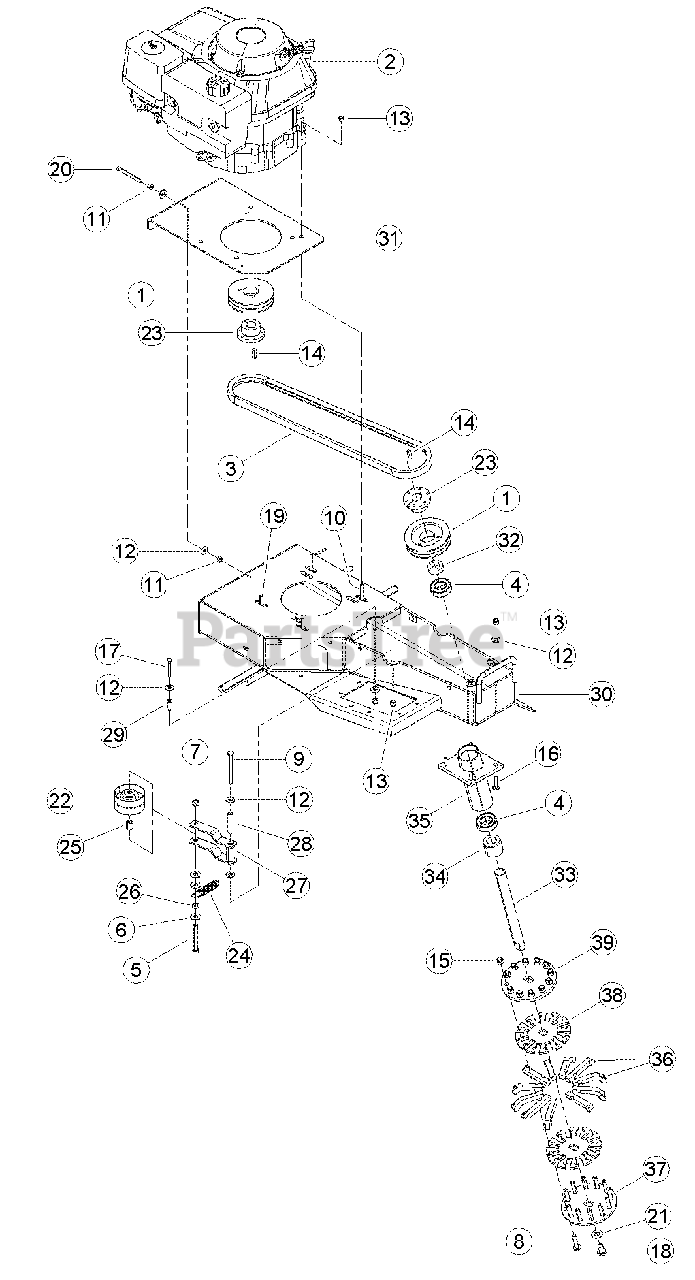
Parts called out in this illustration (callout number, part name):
1	SHEAVE, 3V4.5-2 GROOVE SH
2	ENGINE, 11 HP HONDA GXV
3	BELT, 3VX530 DOUBLE BANDED
4	BEARING, 1 IN. BALL
5	BOLT, 3/8 X 3 HEX HD GR5 ZP
6	WASHER, 3/8 FLAT ZP
7	NUT, 3/8 CENTERLOCK ZP
8	BOLT, 3/8 X 1-3/4 CRG GR5 ZP
9	BOLT, 5/16 X 3-1/2 HEX HD ZP
10	BOLT, 5/16 X 2 HCS GR5 ZP
11	NUT, 5/16 HEX NC ZP
12	WASHER, 5/16 FLAT ZP
13	NUT, 5/16 NE NYLOCK ZP
14	KEY, 1/4 SQUARE X 1 LONG
15	NUT, 3/8 NE NYLOCK ZP
16	BOLT, 5/16 X 1-1/4 CRG GR5 ZP
17	BOLT, 5/16-18 X 1-3/4 HCS GR5 ZP
18	BOLT, 1/2-20 X 3/4 HEX HD GR5 NF ZP
19	BOLT, 5/16 X 1-1/4 HCS NF GR5 ZP
20	SCREW, 5/16 X 3 SQ HD SET
21	WASHER, 1/2 HI-STRENGTH SAE ZP
22	PULLEY, 3-1/4 FLAT IDLER
23	BUSHING, SH 1"
24	SPRING, 3/4"OD EXTENSION
25	TUBE, SPACER 3/4" LONG IDLER
26	SPACER IDLER PIVOT
27	WELDMENT, 2 BELT IDLER
28	PIVOT TUBE
29	SPACER, .54 X .88
30	WELDMENT, STUMPGRINDER FRAME
31	PLATE, ENGINE SLIDE
32	SPACER, 1-1/2 X 1/2
33	SPINDLE, CUTTER SG 12 BLADE
34	TUBE, SPACER 1-3/4 X 1.520
35	WELDMENT, SPINDLE HUB
36	KIT, 12 BLADE CUTTER REPLACEMENT
37	PLATE, COVER STUMPGRINDER HEAD
38	PLATE, SPACER STUMPGRINDER HEAD
39	PLATE, DISK STUMPGRINDER HEAD
